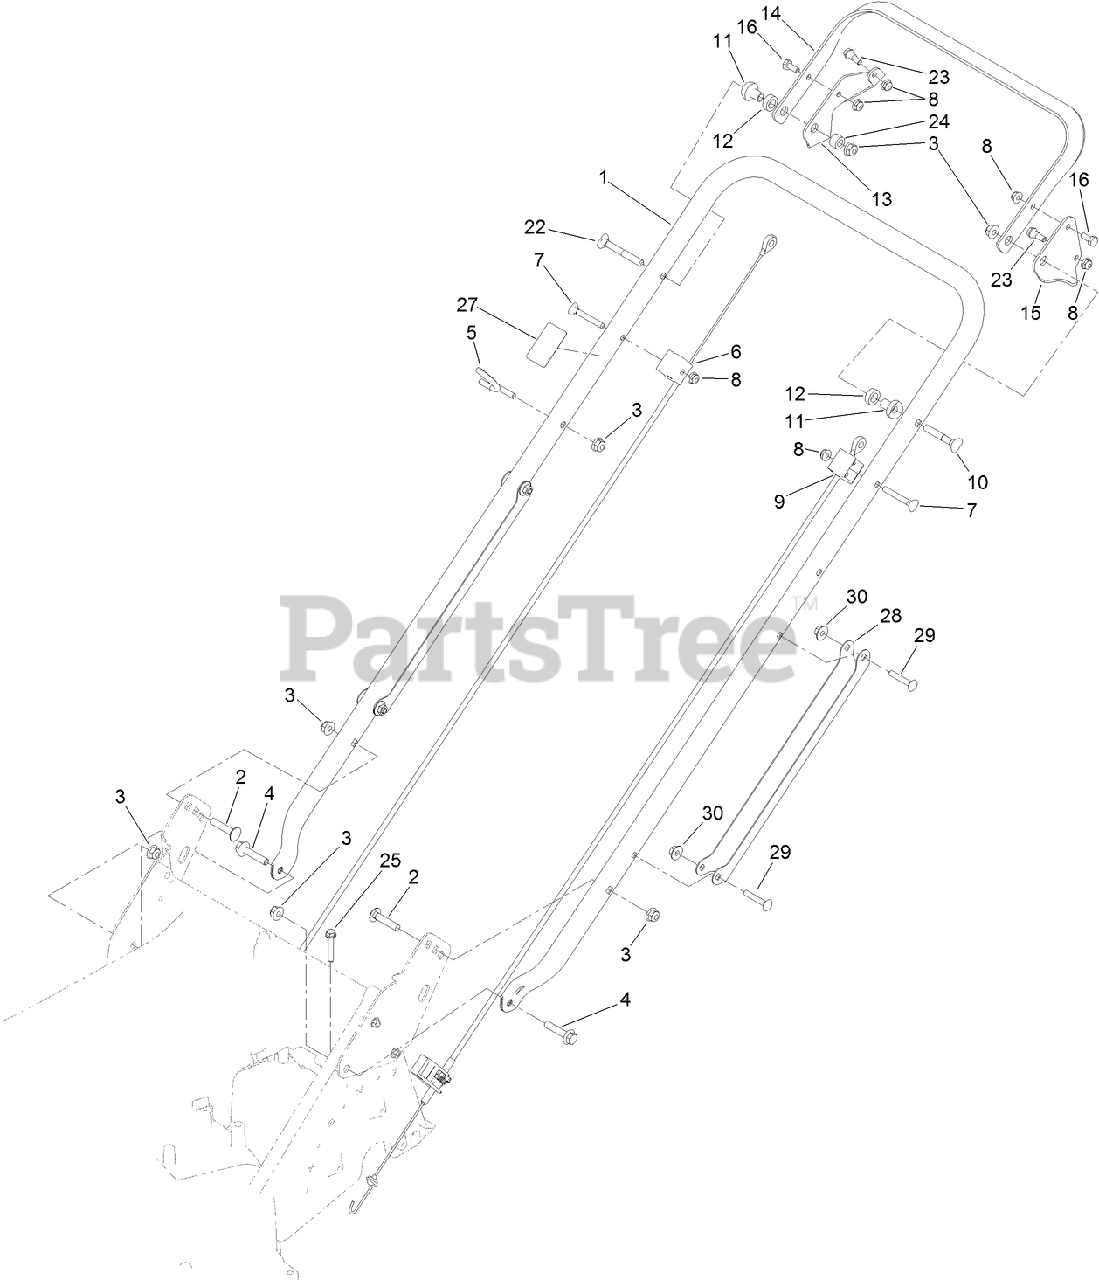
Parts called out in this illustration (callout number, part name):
2	BOLT-CARR
3	NUT-HF, NI
4	SCREW-HHF
5	GUIDE,ROPE
7	SCREW
8	NUT-HF
10	SCREW-HANDLE
11	SPACER-SUPPORT
12	SPACER-NYLON
13	BRACKET-CONTROL, BRAKE
14	BAR-CONTROL, ZONE START
15	LEVER-CONTROL, TRACTION
16	SCREW-HH
22	SCREW-HANDLE
23	BOLT-SHOULDER
24	SPACER
25	SCREW-HWH
27	DECAL-PRIMER
28	GUARD-CABLE, HANDLE
29	SCREW-CARR
30	NUT-HF
